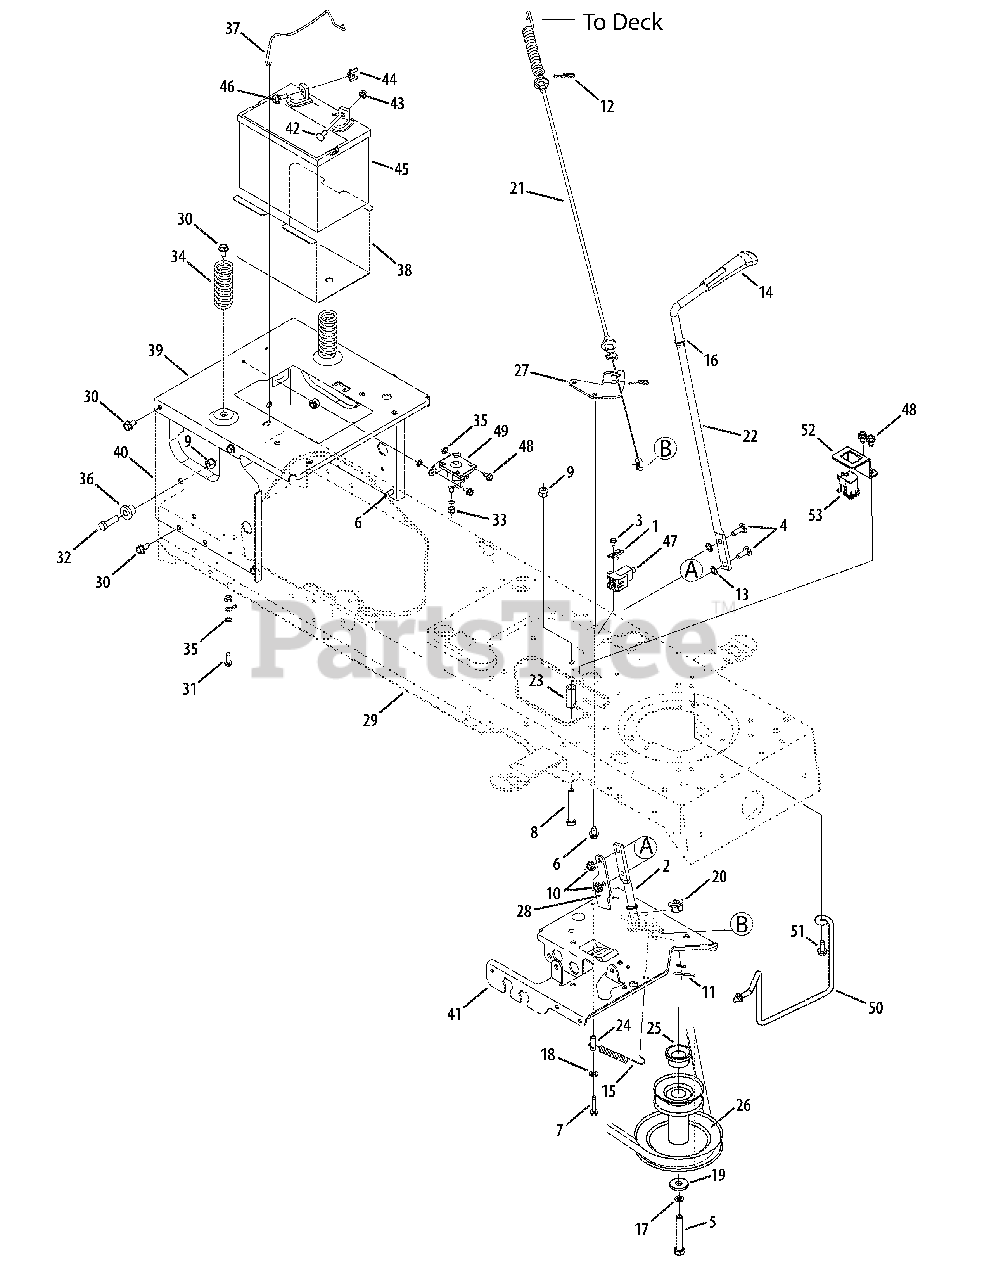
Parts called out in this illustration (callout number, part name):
1	Plate, Switch
2	Lever Assembly, Engagement
3	Screw, #10-16, 0.500
4	Screw, Carriage, 5/16-18, 1.00
5	Screw, 7/16-20, 3.25 42" Deck
6	Screw, 5/16-18, 0.500
7	Screw, 1/4-20 x 1.50
8	Screw, 3/8-16 x 2.25
9	Nut, Flange Lock, 3/8-16, GrF
10	Nut, Flange Lock, 5/16-18, Gr5
11	Pin, Cotter, 1/8 x 1.00
12	Click Pin
13	Nut, Speed, .3125 ID
15	Extension Spring, .38 OD x 3.9 Lg
16	Washer, Flat, .510 x .750 x .033
17	Washer, Lock, 7/16
18	Washer, Flat, .28 x .74 x .063
19	Washer, Flat, .450 x1.250 x.164
20	Bearing, Flange, Hex Split .500 ID
21	Deck Engagement Cable
22	Engagement Handle, Deck
23	Spacer, .385 ID x .635 OD x 1.54
24	Spacer, .260 x .372 x 1.030 Lg.
25	Spacer, 1.010 x 1.40 x .825
26	Pulley, Engine, 42" Deck
27	Cable Bracket
28	Stop Bracket, Engagement
29	Frame Assembly, Lower
30	Screw, 5/16-18 x 0.625
31	Screw, 1/4-20, 0.750
32	Screw, 3/8-16, 1.25, Gr5
33	Nut, Flange Lock, 1/4-20, GrF
34	Spring, Compr., 1.71 x 3.735 x .238
35	Washer, Lock, 1/4, External
36	Spacer, Shoulder, .38 x 1.0 x .70
37	Hold Rod, Battery
39	Seat Bracket, Frame
41	Support Bracket, Steering
42	Hex Head Flange Screw
43	Nut, Sems, 1/4-20
44	Nut, Wing, 1/4-20
45	Battery, 245 CCA
46	Screw, Shoulder, .250 x .150
47	Switch, Interlock
48	Screw, 1/4-20, 0.50
49	Solenoid, 12V, 100 Amp
50	Belt Keeper Rod Assembly 42" Deck
51	Screw, 5/16-18, .750 42" Deck
52	Parking Brake Switch Bracket
53	Snap Mount Switch
